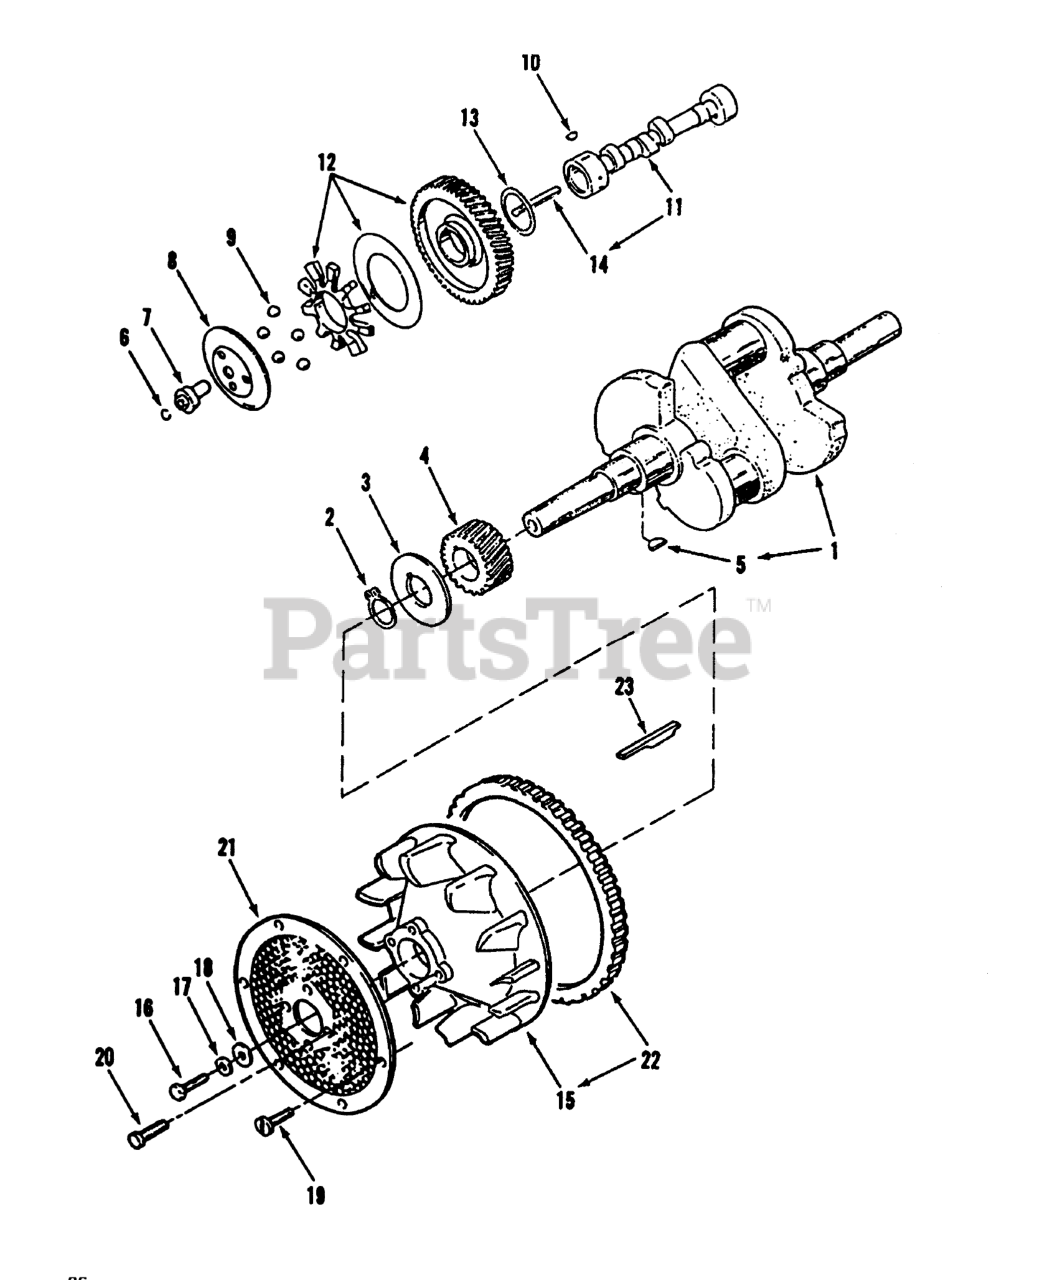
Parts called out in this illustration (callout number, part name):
1	CRANK-SHAFT
3	Washer
4	Gear
5	Key
6	Retaining Ring
7	Governor Cup Hub
8	Cup-Governor
9	BEARING
11	Camshaft (Includes Item 13)
12	Camshaft Gear (Includes Gear, Spacer, & Plate)
13	Washer
14	Pin
15	Flywheel (Includes Ring Gear)
16	Screw
17	WASHER-FLAT
18	Washer
19	Bolt
20	SCREW - CAP HEX HEAD
21	Screen
23	KEY - MACHINE
